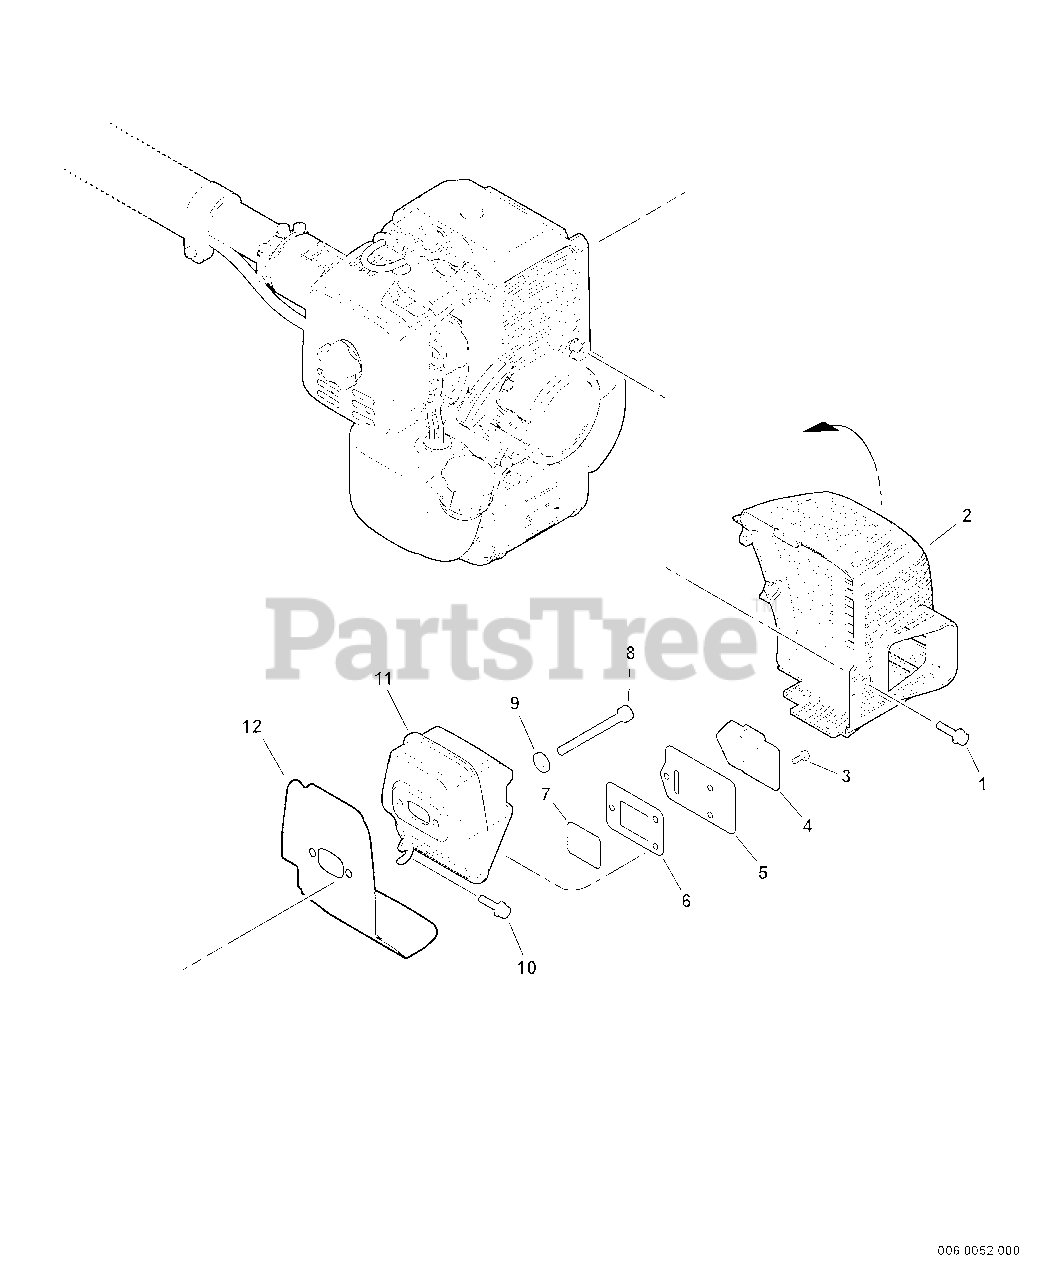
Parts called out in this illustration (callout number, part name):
1	SCREW - 5X14
2	COVER, EXHAUST
3	SCREW - 4X14
4	GUIDE, EXHAUST
5	GASKET, EXHAUST
6	GASKET, EXHAUST
7	SCREEN, SPARK ARRESTOR
8	SCREW - 5X60
9	WASHER - 5
10	SCREW - 5X12
11	MUFFLER
12	SHIELD, EXHAUST
